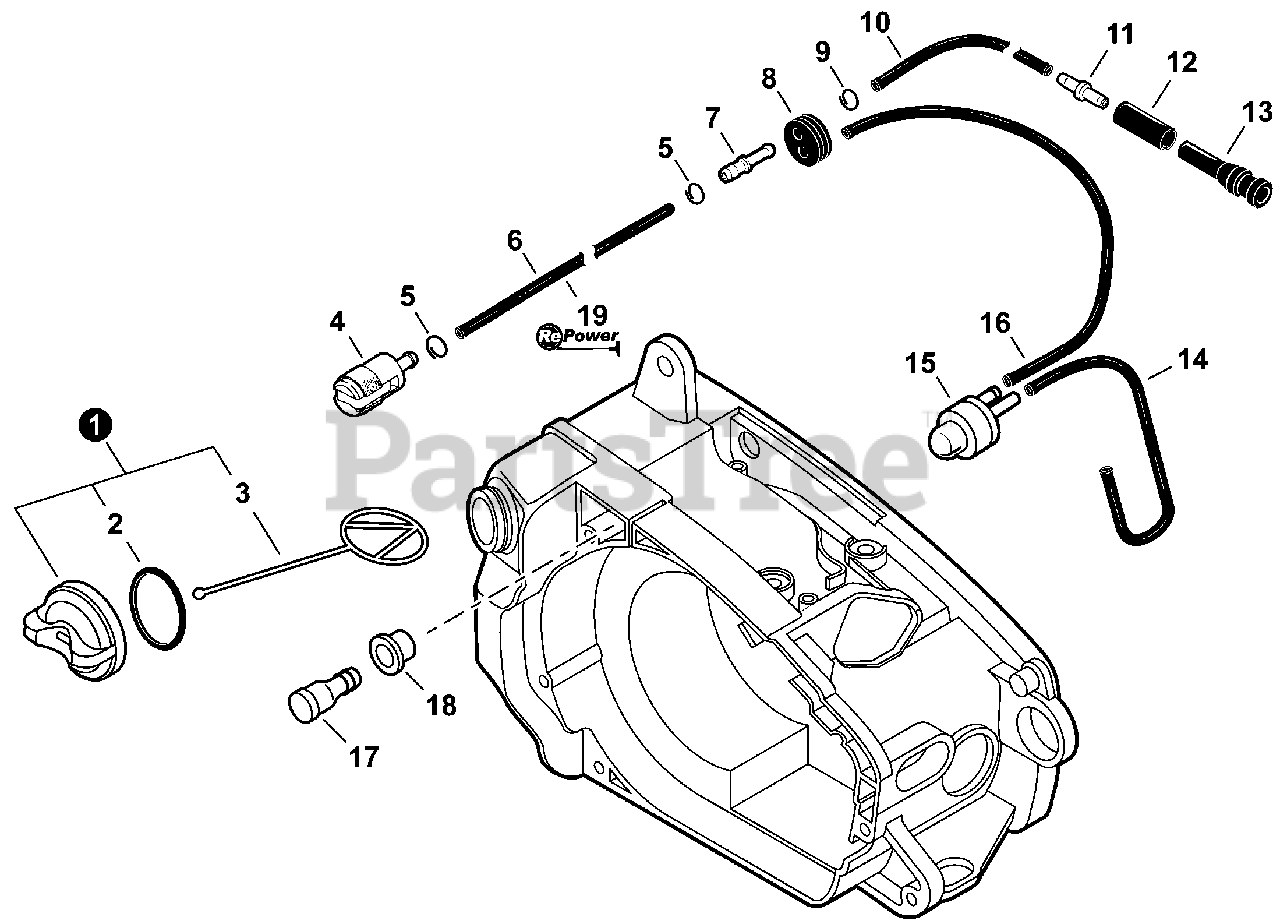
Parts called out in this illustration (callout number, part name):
1	CAP ASSY, FUEL - ORANGE
3	CONNECTOR, CAP L= 60mm
4	FILTER, FUEL
5	CLIP Ø6
6	PIPE 3×5×75
7	CONNECTOR, PIPE Ø5ר3.5
8	GROMMET, FUEL
10	PIPE 3×5×145
11	CONNECTOR, PIPE
12	TUBE f6.5×8.5×18
13	PIPE, FUEL 10×6×32
14	PIPE 2.4×5×153
15	BULB, PURGE
16	PIPE 2.4×5×258
17	VENT ASSY
18	GROMMET, FUEL
19	PIPE, BULK - REPOWER 3×5mm BLACK
